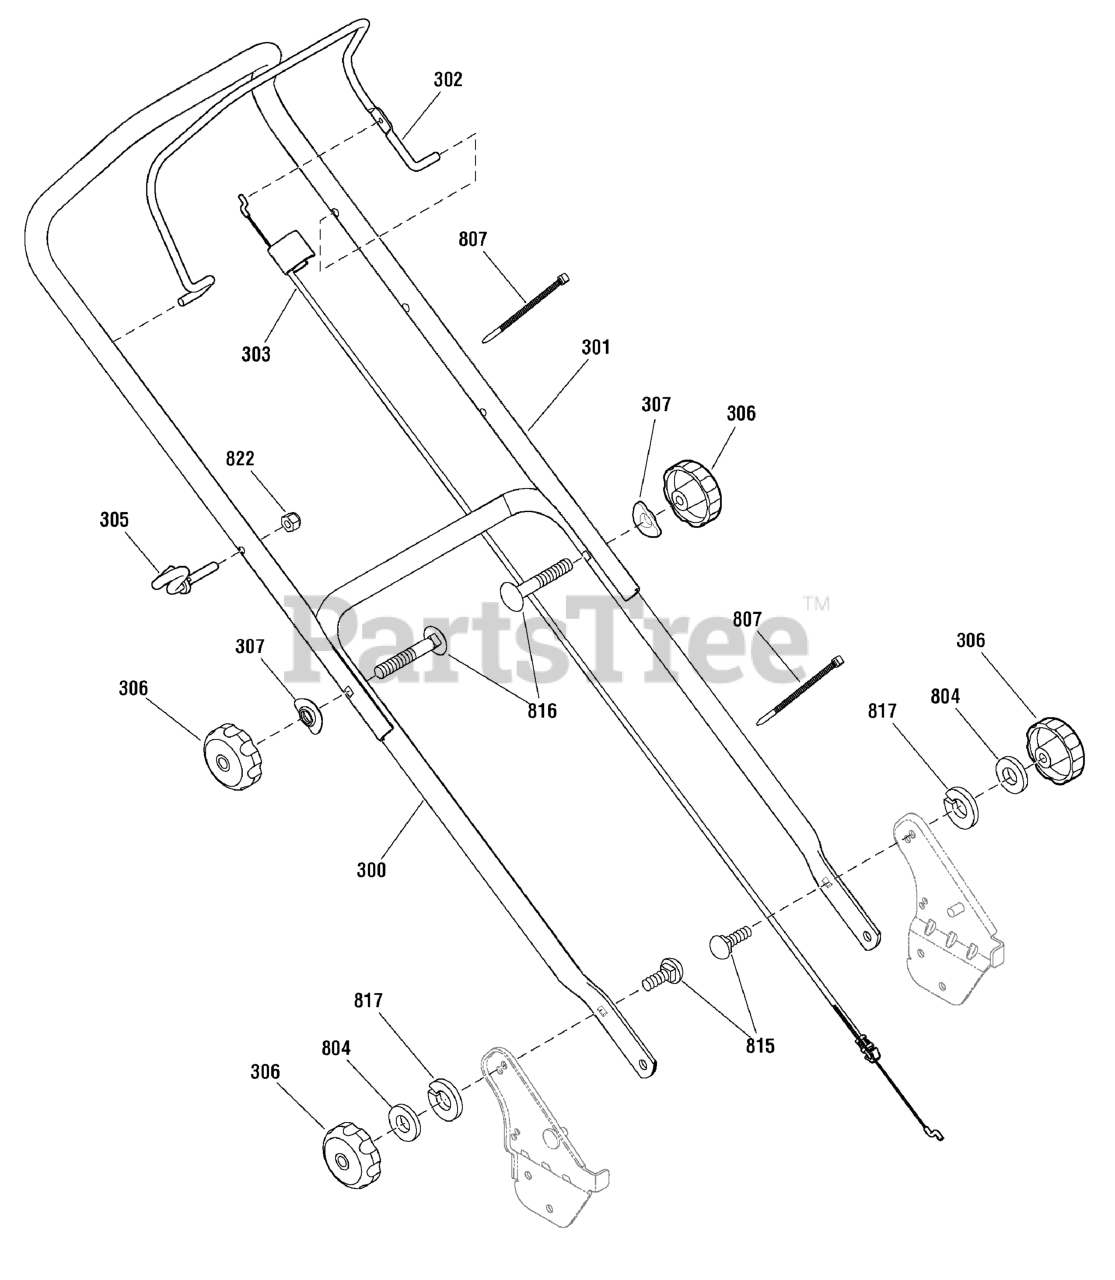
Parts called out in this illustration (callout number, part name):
300	HANDLE, Lower
301	HANDLE, Upper
302	LEVER, Engine Stop
303	CABLE, Engine Stop
305	GUIDE, Rope, 1/4-20
306	KNOB, 5/16-18
307	WASHER, Formed
804	WASHER, 5/8
807	CABLE TIE
815	BOLT, Carriage, 5/16-18 x 1-1/8
816	BOLT, Carriage, 5/16-18 x 2
817	Washer, Lock
822	NUT, Hex, 1/4-20
